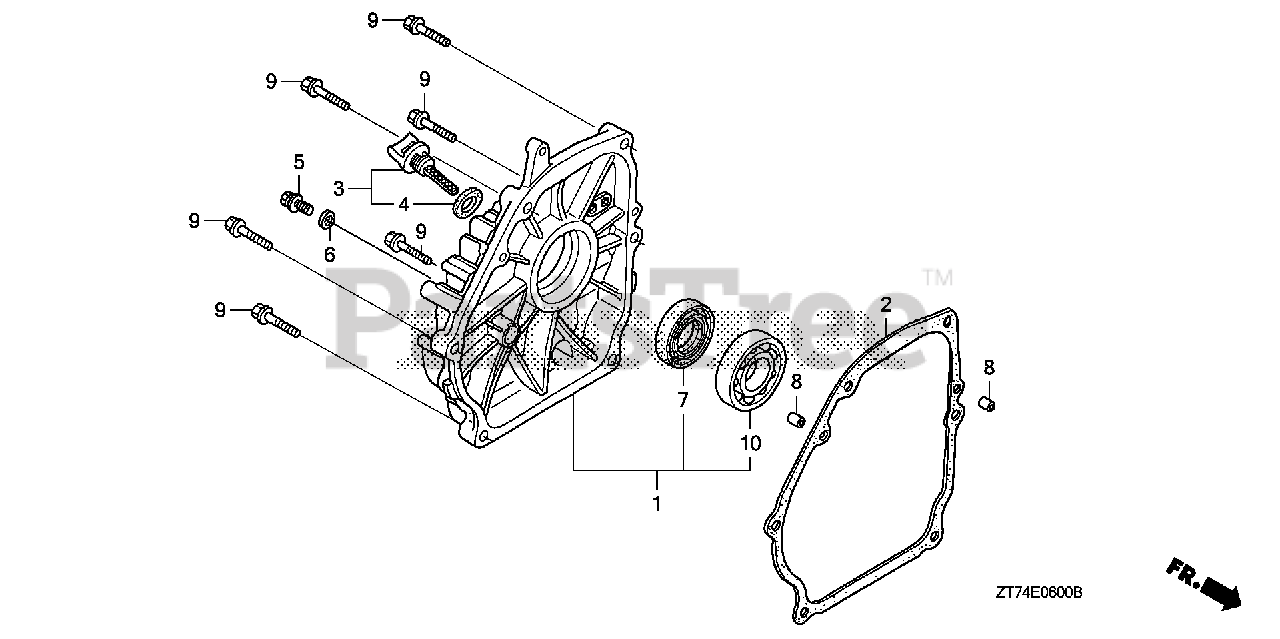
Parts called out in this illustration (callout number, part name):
1	COVER, CRANKCASE
2	GASKET, CASE COVER (NON-ASBESTOS)
2	GASKET, CASE COVER
3	CAP ASSY., OIL FILLER (GRAY)
4	GASKET, OIL FILLER CAP
5	BOLT, DRAIN PLUG
6	WASHER, DRAIN PLUG (10.2MM)
7	OIL SEAL (25X41X6) (NOK)
8	PIN, DOWEL (8X14)
9	BOLT, FLANGE (8X32)
10	BEARING, RADIAL BALL (6205)
